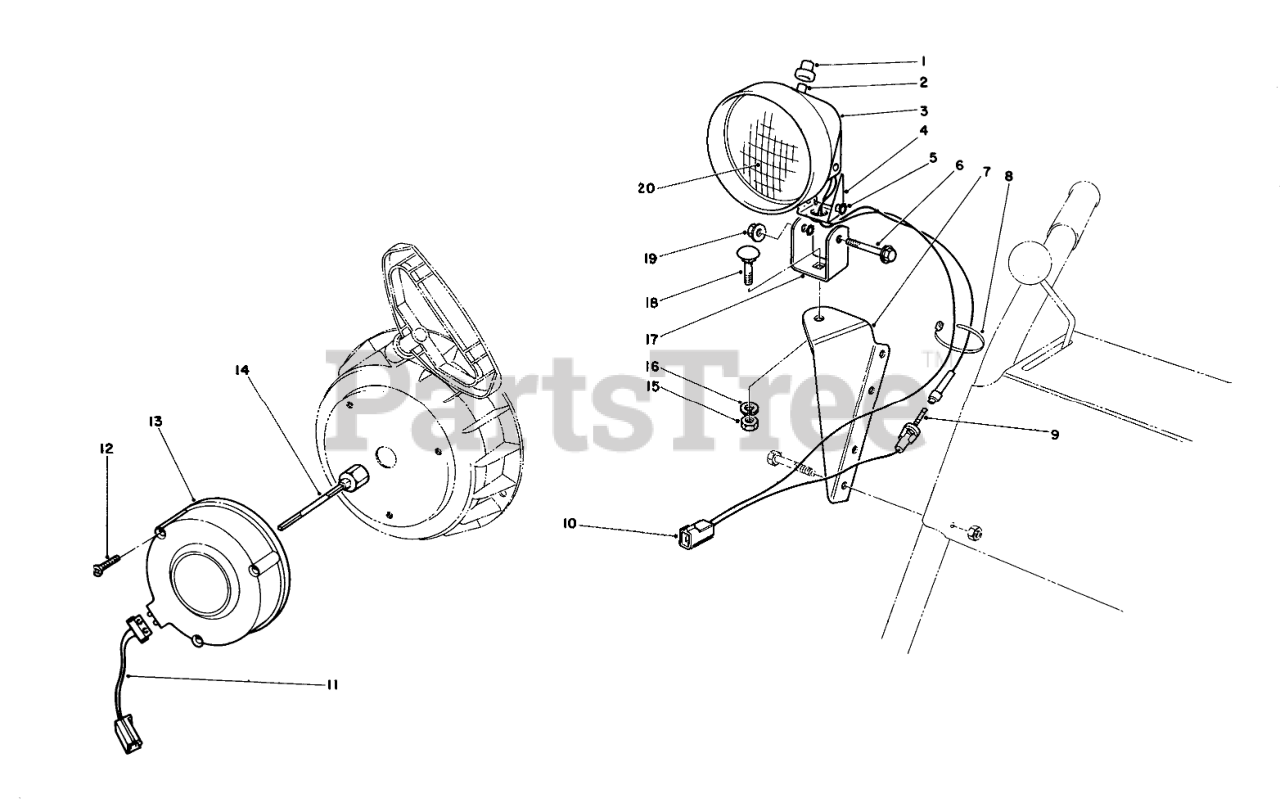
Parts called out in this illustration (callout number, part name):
1	BOOT-SWITCH
5	WASHER-LOCK
6	SCREW-HH
7	MOUNT-LAMP
8	TIE-CABLE
9	Fuse-7 1/2 Amp.
10	WIRE ASM
13	TECUMSEH 1A183-69
15	NUT-HEX
16	WASHER-LOCK
18	BOLT-CARR
19	NUT-HF
